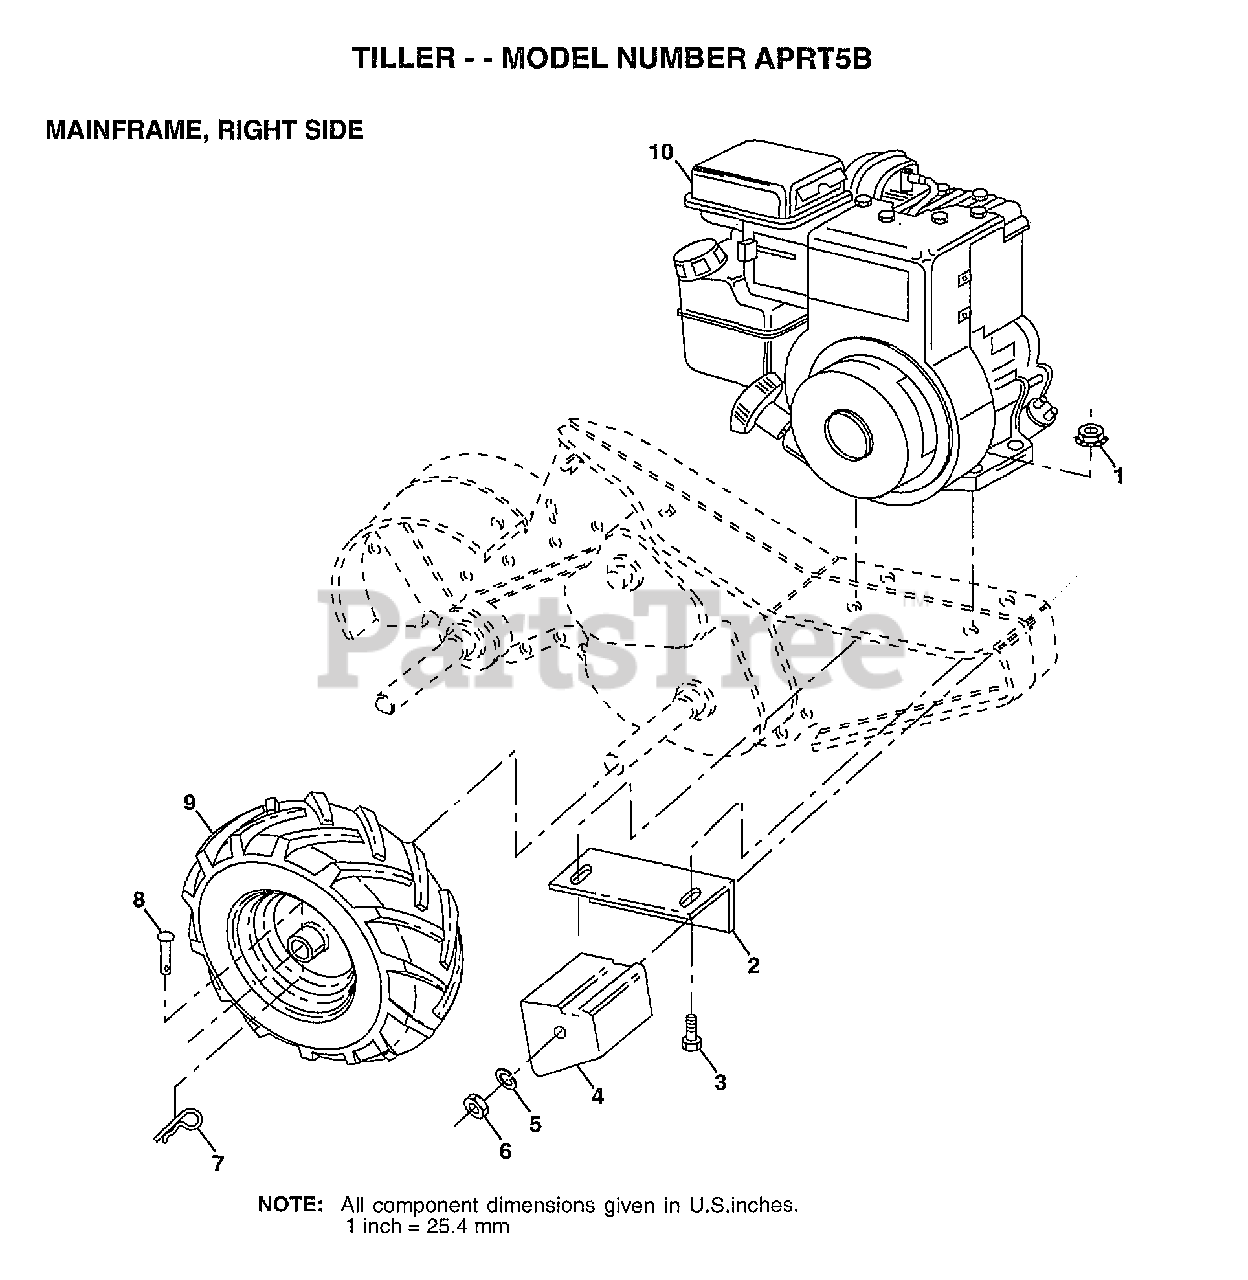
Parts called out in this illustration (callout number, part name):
2	BRACKET RH CRT
3	BOLT.HEX.5/16-1.5
4	COUNTERWEIGHT CRT
5	LOCKWASHER
6	NUT.HEX.3/8-16UNC
7	RETAINER M
8	RIVET.DRILL.1.75
9	TIRE.CHV.13X5.0-6
9	"RIM.ASM.6"".GREY"
